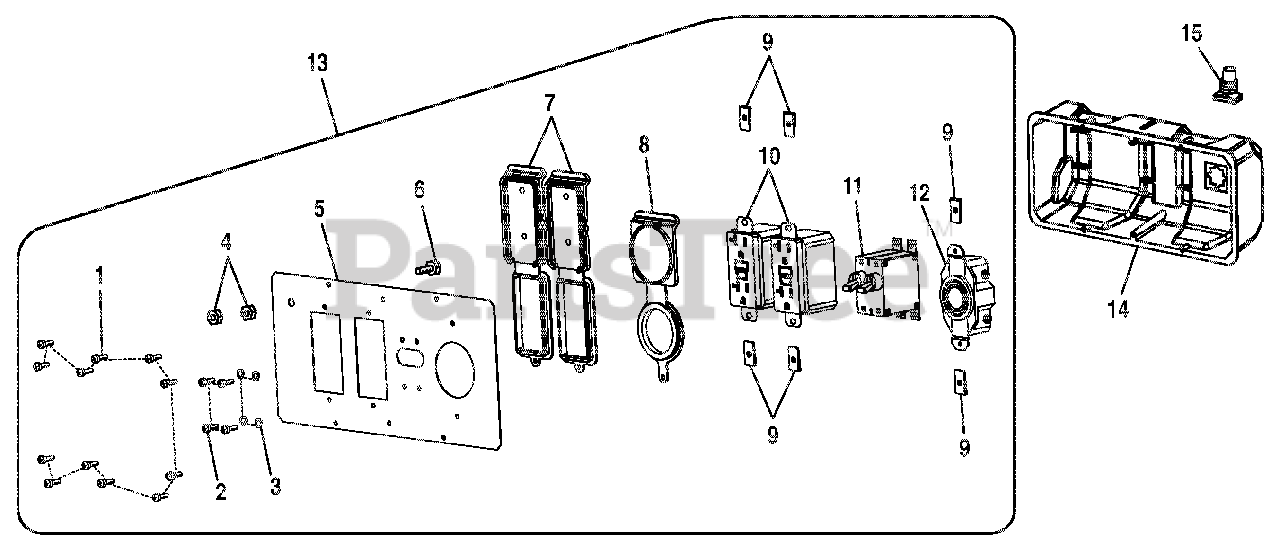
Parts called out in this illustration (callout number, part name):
1	Screw (6-20 x 3/8 in.)
2	Screw (M3 x 6)
3	Lock Washer
4	Hex Nut (1/4-20)
5	Cover Plate
6	Screw (1/4-20 x 5/8 in., Hex Hd.)
7	Outlet Cover (120 Volt)
8	Outlet Cover (240 Volt)
10	Duplex Receptacle (120 Volt)
11	Circuit Breaker (20 Amp, 125 Volt)
12	Twist Lock Receptacle (120/240 Volt, 20 Amp)
13	Front Panel (Inc. Key Nos. 1-12)
14	Rear Control Panel
15	Rubber Boot
